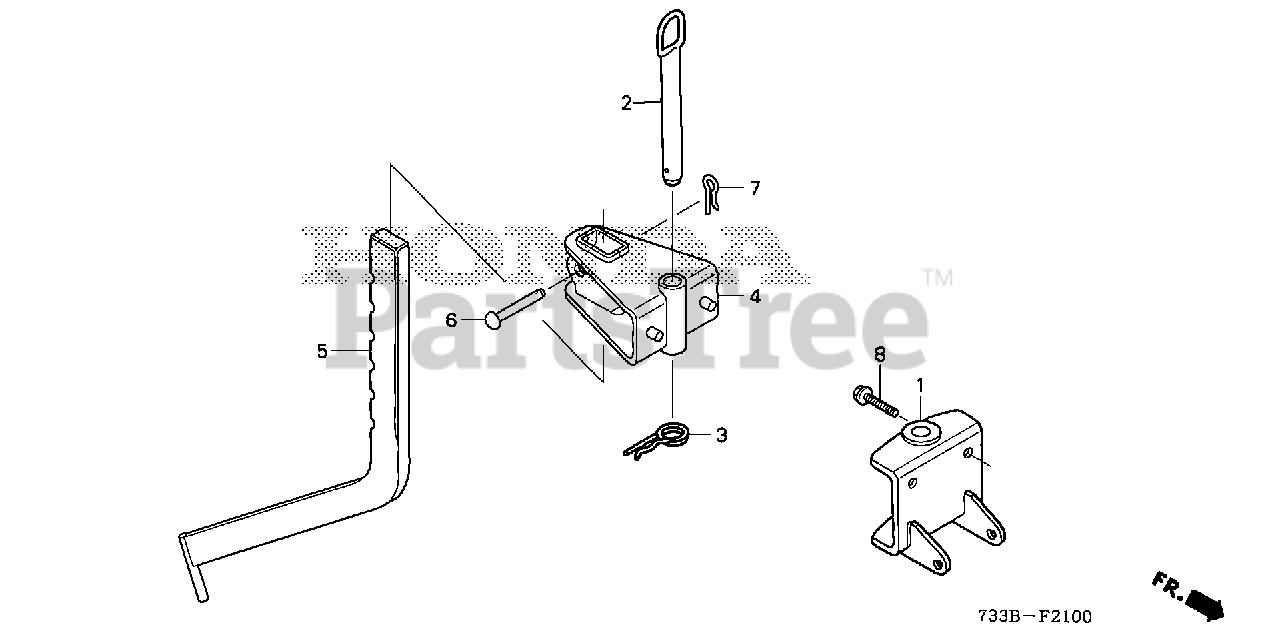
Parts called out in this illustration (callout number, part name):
1	BOX, HITCH
2	PIN, HITCH
4	HITCH, ATTACHMENT
6	PIN (10X53.5)
7	PIN, LOCK (10MM)
8	BOLT, FLANGE (8X20)
